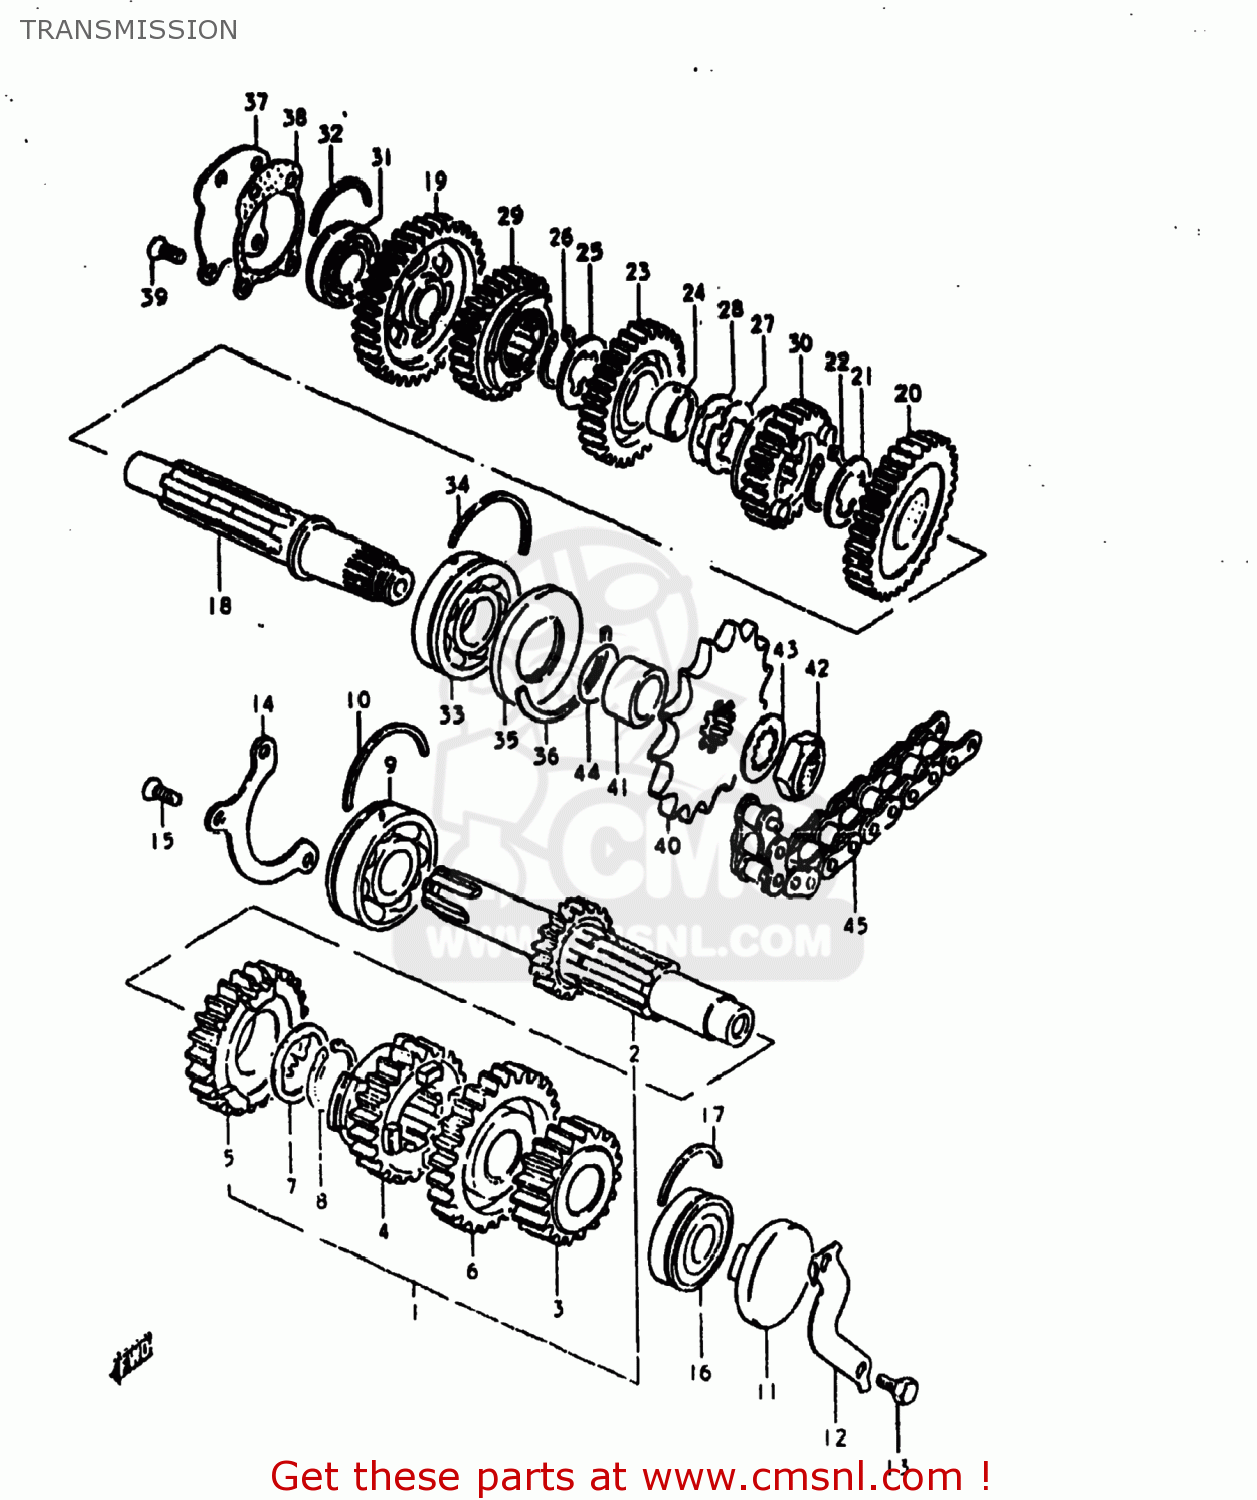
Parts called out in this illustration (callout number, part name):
1	SHAFT ASSEMBLY,COUNTER
2	SHAFT,COUNTER
3	GEAR,SECOND DRIVE
4	GEAR,THIRD DRIVE
5	GEAR,FOURTH DRIVE
6	GEAR,FIFTH DRIVE
7	WASHER,LOCK
8	CIRCLIP
9	BEARING(25X62X17)
10	C-RING
11	PLUG
12	RETAINER,CL PUSH ROD OIL SEAL
13	BOLT
14	RETAINER,CNTR SHAFT BEARING
15	SCREW
16	BEARING(20X47X14)
17	C-RING
18	SHAFT,DRIVE
19	GEAR,FIRST DRIVEN
20	GEAR,SECOND DRIVEN
21	WASHER,LOCK
22	CIRCLIP
23	GEAR,THIRD DRIVEN
24	BUSH,3RD DRIVEN GEAR
25	WASHER,LOCK
26	CIRCLIP
27	WASHER,LOCK
28	WASHER
29	GEAR,FOURTH DRIVEN
30	GEAR,FIFTH DRIVEN
31	BEARING
32	C RING
33	BEARING(25X62X17)
34	C-RING
35	SEAL,OIL(32X62X7)
36	C RING
37	PLATE,DRIVE SHAFT
38	GASKET,DRIVESHAFT PLATE (MCA)
39	SCREW
40	SPROCKET,ENGINE
41	SPACER(25X32X18.6)
42	NUT
43	WASHER
44	O RING(D:1,ID:24.5)
45	CHAIN ASSEMBLY,DRIVE
